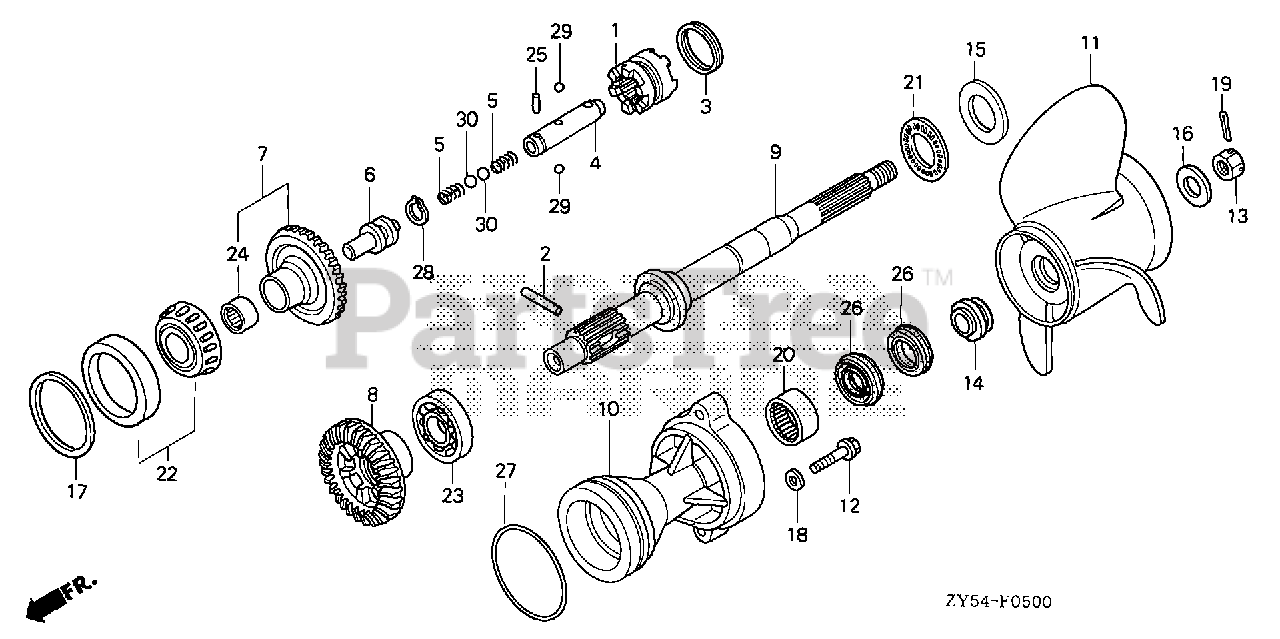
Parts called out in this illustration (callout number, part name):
1	SHIFTER, CLUTCH
2	PIN, SHIFTER (8X47)
3	RING, CROSS PIN
4	SLIDER, SHIFT
5	SPRING, SHIFT
6	PLATE, SHIFT
7	GEAR, BEVEL (FORWARD 30T)
8	GEAR, BEVEL (RVS. 30T)
9	SHAFT, PROPELLER
10	HOLDER, PROPELLER SHAFT *NH282MU* (OYSTER SILVER METALLIC-U)
11	PROPELLER, THREE-BLADE (15-1/4X15) (AL)
11	PROPELLER, THREE-BLADE (15X17) (AL)
11	PROPELLER, THREE-BLADE (14-3/4X19) (AL)
11	PROPELLER, THREE-BLADE (14-1/2X21) (AL)
11	PROPELLER, THREE-BLADE (15-1/2X13) (AL)
11	PROPELLER, THREE-BLADE (14-1/4X23) (AL)
11	PROPELLER, THREE-BLADE (14-1/2X15) (SUS)
11	PROPELLER, THREE-BLADE (14-1/4X17) (SUS)
11	PROPELLER, THREE-BLADE (14X19) (SUS)
11	PROPELLER, THREE-BLADE (14X21) (SUS)
11	PROPELLER, THREE-BLADE (14-1/2X23) (SUS)
11	PROPELLER, THREE-BLADE (14X25) (SUS)
11	PROPELLER, THREE-BLADE (15-1/2X13) *NH283* (AL) (STIN GRAY)
11	PROPELLER, THREE-BLADE (15-1/4X15) *NH283* (AL) (STIN GRAY)
11	PROPELLER, THREE-BLADE (15X17) *NH283* (AL) (STIN GRAY)
11	PROPELLER, THREE-BLADE (14-3/4X19) *NH283* (AL) (STIN GRAY)
11	PROPELLER, THREE-BLADE (14-1/2X21) *NH283* (AL) (STIN GRAY)
11	PROPELLER, THREE-BLADE (14-1/4X23) *NH283* (AL) (STIN GRAY)
12	BOLT, FLANGE (10X40)
13	NUT, CASTLE (18MM)
14	WASHER, PROPELLER THRUST
15	WASHER, THRUST BEARING
16	WASHER, PROPELLER
17	SHIM A, BEVEL (0.10)
17	SHIM B, BEVEL (0.15)
17	SHIM C, BEVEL (0.30)
17	SHIM D, BEVEL (0.50)
18	WASHER, PLAIN (10MM)
19	PIN, SPLIT (4.0)
20	BEARING, NEEDLE (30X37X26)
21	BEARING, THRUST (F)
22	BEARING, TAPER (50X90X28)
23	BEARING, RADIAL BALL (50X90X20)
24	BEARING, NEEDLE (25X32X26)
25	ROLLER (3X12.8)
26	SEAL, WATER (30X45X7)
27	O-RING (105X3.1)
28	CIRCLIP, OUTER (14MM)
29	BALL, STEEL (#7) (7/32)
30	BALL, STEEL (#9) (9/32)
